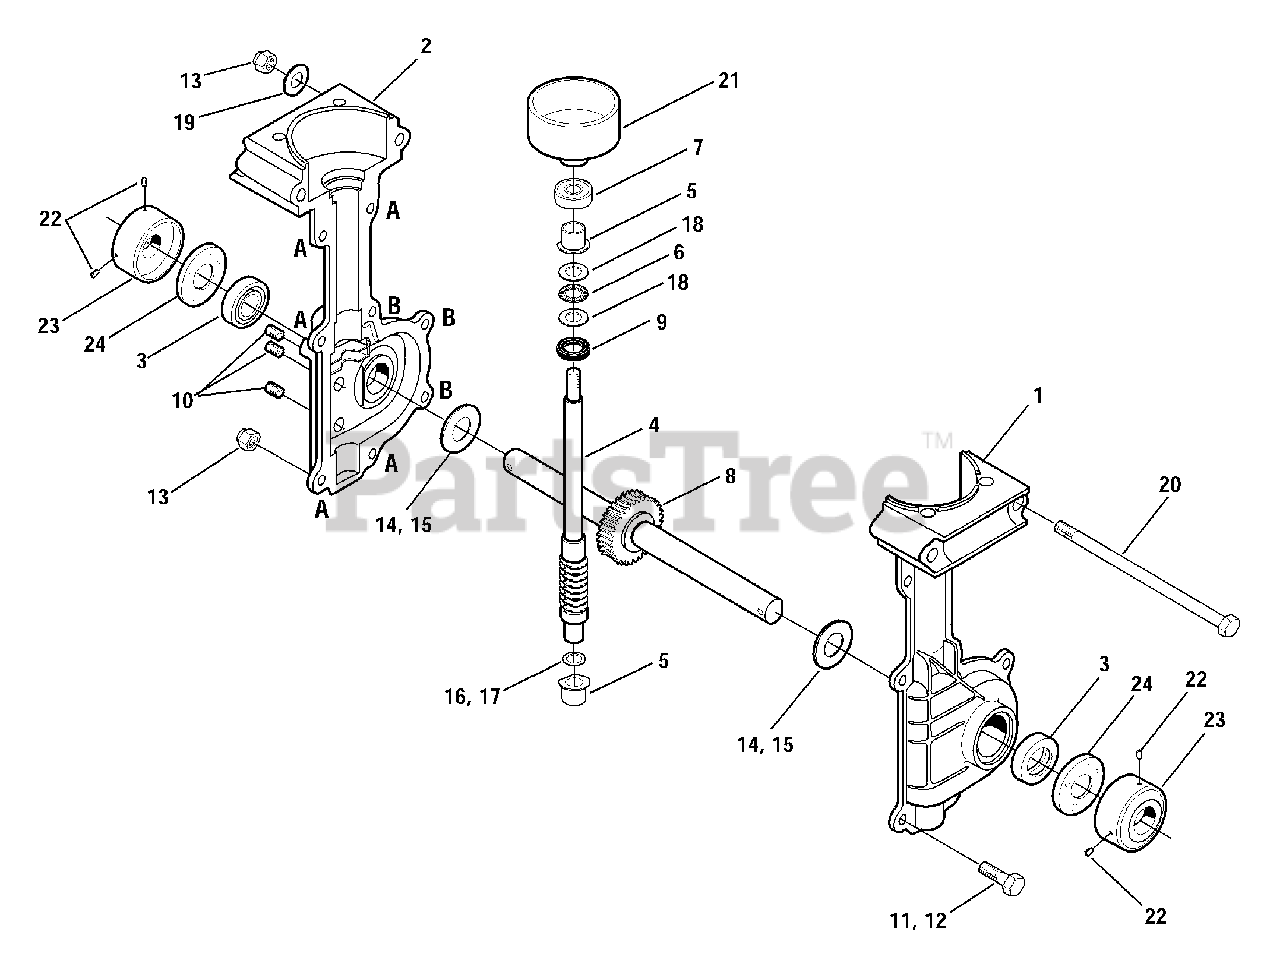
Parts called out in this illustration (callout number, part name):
1	Transmission Case - left-side
2	Transmission Case - right-side
3	Oil Seal
4	Worm Input Shaft Assembly
5	Input Bearing
6	Thrust Bearing
7	Ball Bearing
8	Shaft Assembly
9	Oil Seal, Input
10	Plug, 1/8
11	Hex Screw, 1/4-20 x 7/8
12	Hex Screw, 1/4-20 x 1
13	Locknut, Nyloc, 1/4"-20
14	Thrust Washer, output (.050")
15	Thrust Washer, output (.040")
16	Thrust Washer, input (.020")
17	Thrust Washer, input (.035")
18	Thrust Washer
19	Flat Washer, 1/4
20	Hex Hd. Screw, 1/4-20 x 5
21	Clutch Drum and Hub
22	Set Screw, 1/4-28 x 3/8
23	Dust Cover
24	Felt Washer
